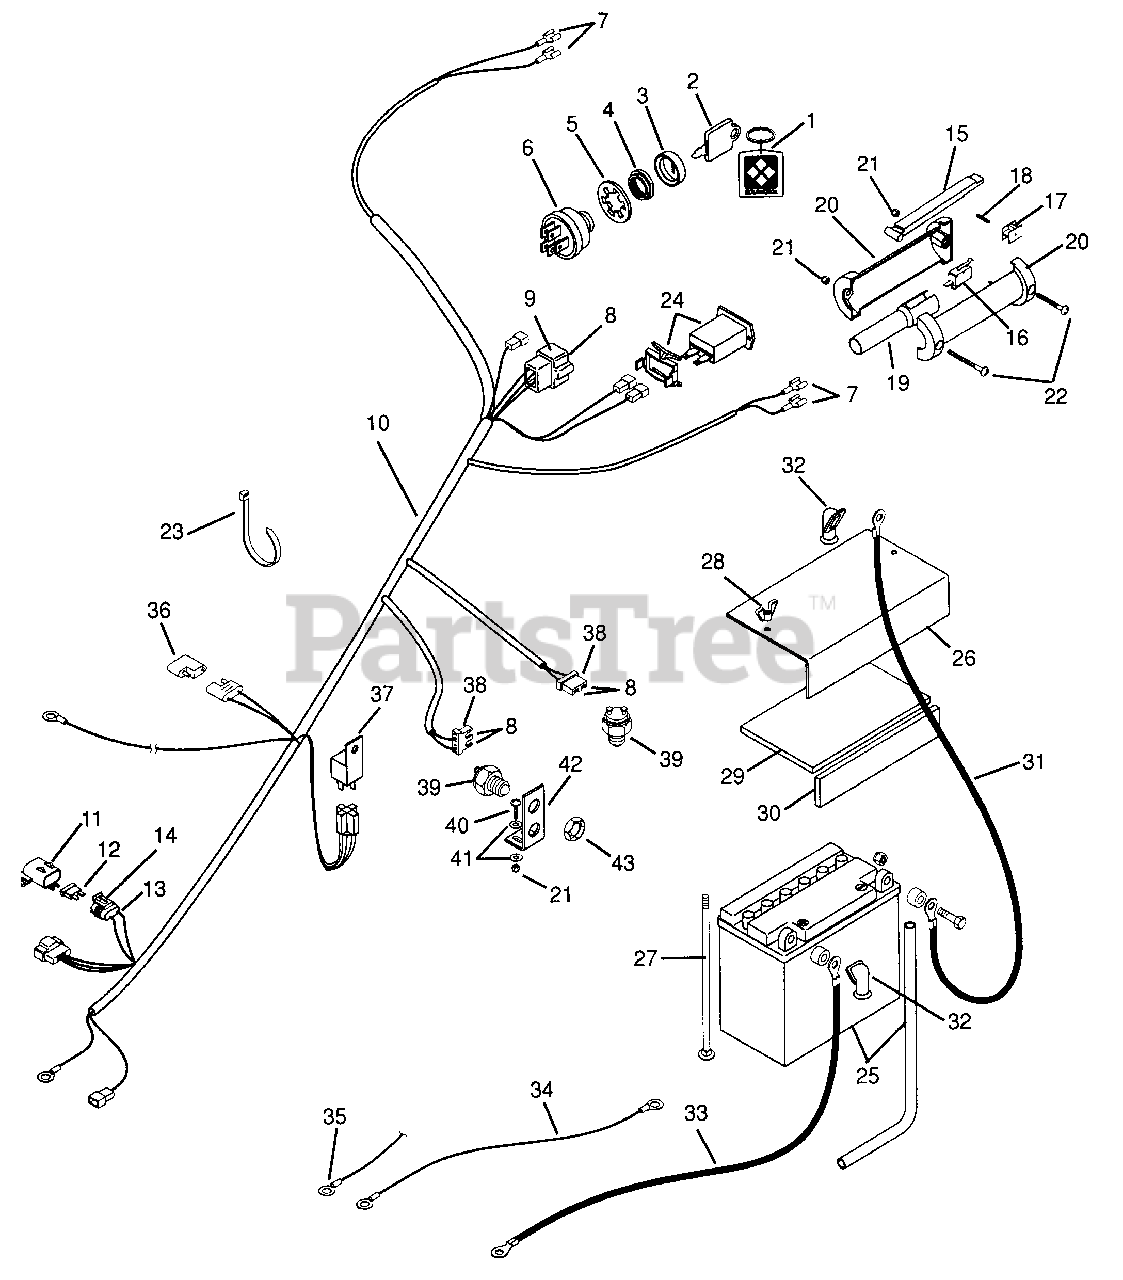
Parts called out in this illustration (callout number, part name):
1	Key Chain
2	Ignition Switch Key
3	Cap, Ignition Switch
4	Nut-Panel .625-32
5	Washer-Lock .625
6	Key Switch
7	Terminal, Female
8	Terminal
9	Connector
10	Wire Harness, Pro 200
11	Cover
13	Terminal, For 14-16 Ga Wire
14	Assembly, Connector Weather Tight
15	Lever
16	Switch
17	Holder, Switch
18	Pin-Roll .094 x .750
19	Insert, Handlebar
20	Handle, Left Hand and Right Hand
21	Nut-Locking 10-24
22	Screw-Machine 10-24 x 1.50
23	Tie Wrap, Black
24	Hour Meter
25	Battery, 12 Volt
26	Cover, Battery
27	Bolt-Round Head Square Neck .25-20 x 7.00
28	Nut-Wing .250-20
29	Pad, Battery
30	Pad, Battery
31	Cable, Battery to Solenoid
32	Boot, Insulator
33	Cable, Negative Battery
34	Wire, Ground
35	Terminal, Ring Tongue
36	Molded Diode Plug - Clear 1 AMP
37	Relay
38	Connector, 2-Wire Switch
39	Switch-Neutral Start N.C
40	Screw-Machine 10-24 x .750
41	Washer-Flat-Steel .219 x .50 x .049
42	Bracket-Interlock Switch
43	Nut-Stamped .56-18
